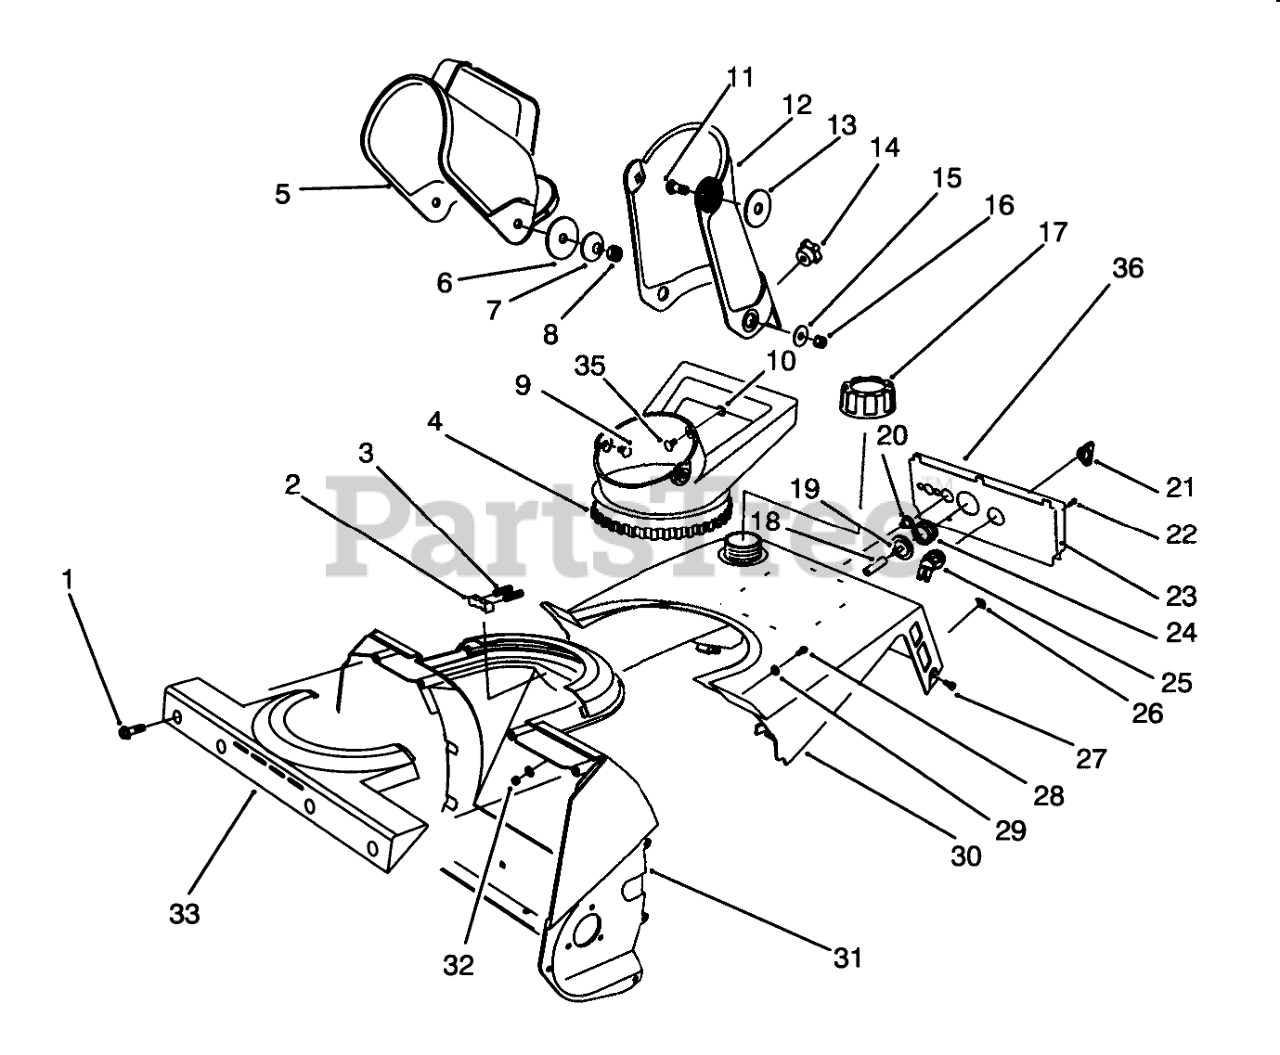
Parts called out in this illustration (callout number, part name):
1	SCREW-PLASTIC
2	DETENT-CHUTE
3	SPRING-COMPRESSION
4	HANDLE-CHUTE
5	DEFLECTOR-CHUTE
6	WASHER-FLAT
7	WASHER-BELLEVILLE
8	NUT-LOCK, NI
9	SCREW-HH
10	PUSHNUT-RETAINER, BOLT
11	BOLT-CARR
12	CHUTE
13	Washer-Rubber
14	KNOB-CHUTE
15	WASHER-FLAT
16	NUT-LOCK, NI
17	CAP-FUEL ASM
18	HOSE-PRIMER
19	BODY-PRIMER
20	GUIDE-ROPE, STARTER
21	KEY-IGNITION
22	SCREW-SHWH, THREAD FORMING
23	Panel-Control
24	BULB-PRIMER
25	SWITCH
27	SCREW-THREAD FORMING
28	SCREW-PPH
29	WASHER-FLAT
30	Shroud-Upper
31	HOUSING
32	NUT-LOCK, NI
33	RETAINER-CHUTE
35	SCREW-CARR
36	DECAL - CONTROL PANEL
